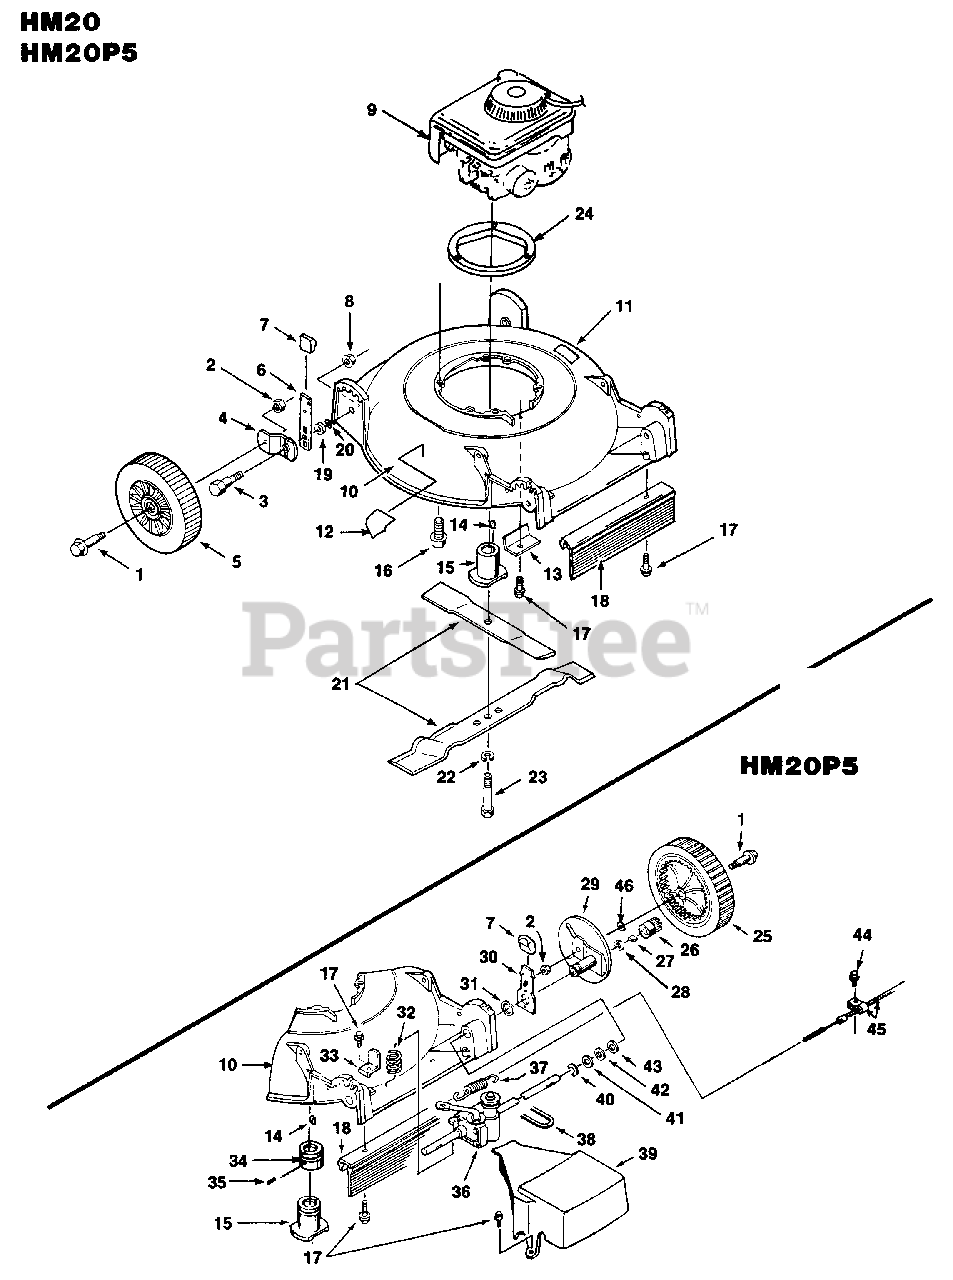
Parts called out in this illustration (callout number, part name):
1	AXLE ASSY.
2	HEX NUT (CM20P4) TBO
3	Bolt, TBO
4	ARM - Wheel hgt. adj.
5	WHEEL & TIRE
6	Index Front Spring, Tbo
7	KNOB
8	HEX WASHER NUT-TBO
11	DECAL- Warning
12	DECAL-CPSC
13	Cover - belt opening
15	ADAPTER
16	Bolt - hex 3/8-16 x 1 1/2
17	SCREW - 1/4-20 x 3/4" Hex Tap
18	DEFLECTOR TBO
19	SPACER - Wheel hgt. adj.
20	FLAT WASHER(HSD'S) TBO
22	WASHER - Lock 3/8"
23	Screw-Hex hd. 3/8-24 x 2"
24	RING - Engine
25	DRIVE WHEEL TBO
26	PINION- R.H.
28	WASHER-TBO
29	DRIVE WHEEL SUPPORT-TBO
30	INDEX SPRING-TBO
31	SPACER - Rear hgt. adj.
33	Bracket - Transmission
34	PULLEY- Drive
35	Screw - set 1/4-20 x 3/8
36	HOUSING - Gear box
37	SPRING - Ext.
38	BELT
39	COVER- Drive
44	BOLT
45	Pulley - drive
